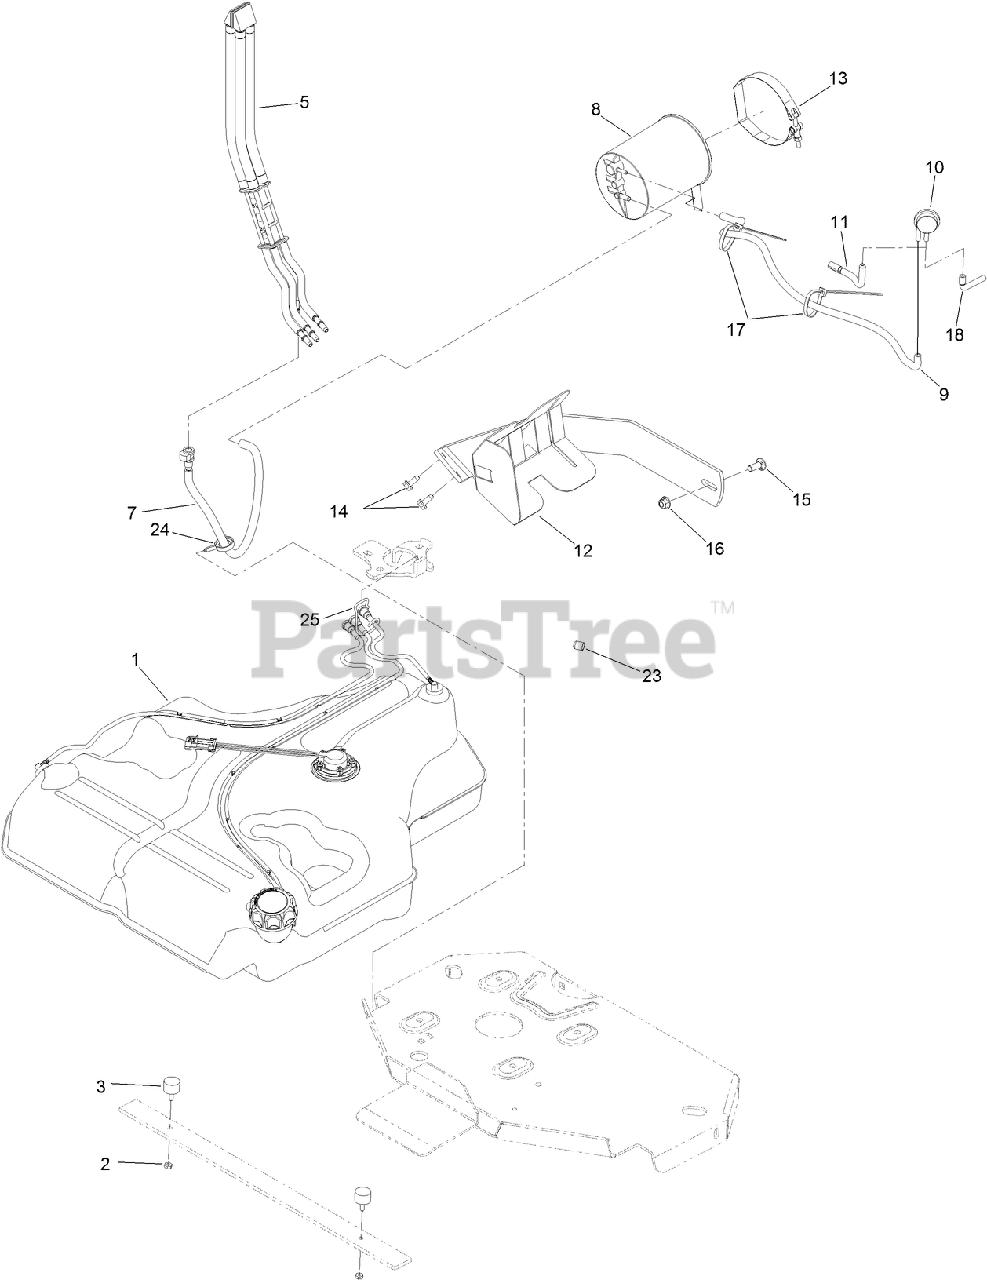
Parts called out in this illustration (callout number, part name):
1	FUEL TANK ASM
2	NUT-JAM
3	BUMPER-RUBBER (W/ STUD)
5	FUEL MANIFOLD VENT ASM
7	VENT HOSE ASM
8	CANISTER-CARBON, 1200CC
9	HOSE-VENT, FORMED
10	VALVE-CONTROL, VACUUM
11	HOSE-VENT, FORMED
12	MOUNT-CANISTER
13	CLAMP-T-BOLT
14	SCREW-HWHTF
15	SCREW-CARR
16	NUT-HF, NI
17	TIE-PLASTIC
18	HOSE-VENT, FORMED
23	PLUG-PORT
24	CLAMP-HOSE
25	RETAINER-LINE, VAPOR
